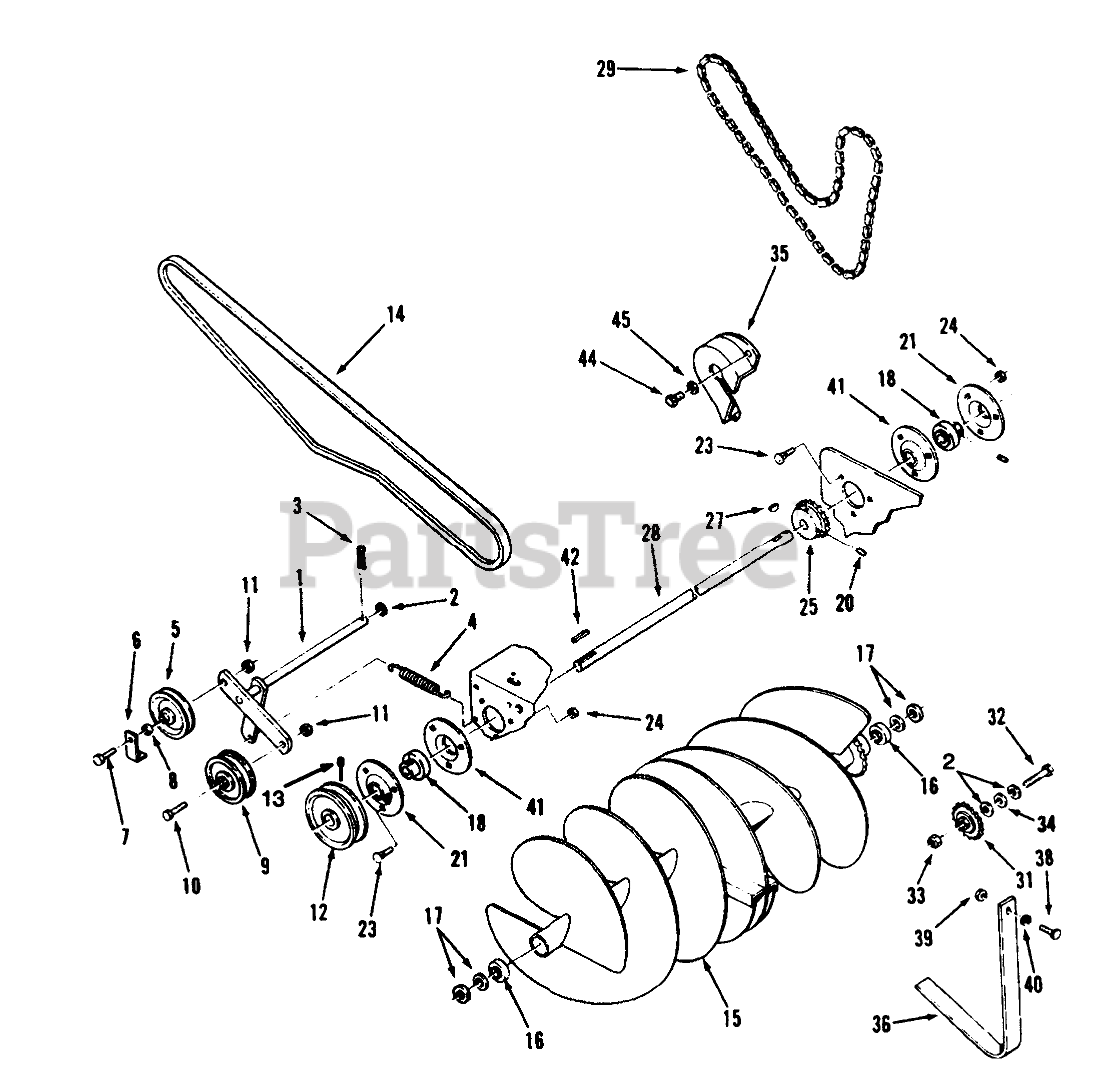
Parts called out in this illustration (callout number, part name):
1	Arm Idler
2	WASHER-FLAT
3	PIN-COTTER
4	SPRING-EXTENSION
5	PULLEY-IDLER
6	Spacer
7	SCREW-HH
8	SPACER
9	PULLEY-IDLER, FLAT
10	SCREW-HH
11	NUT-LOCK, NI
12	PULLEY
13	SCREW-SQH
14	V-BELT
15	Auger
16	BEARING-BALL
17	WASHER-FLAT
18	BEARING AND COLLAR
20	SCREW-SET, HSH
21	FLANGE-ZERK RELUBE
23	BOLT-CARR
24	NUT-LOCK, NI
25	SPROCKET-14T H.T.
27	KEY-WOODRUFF
28	Shaft
29	CHAIN
31	Idler Sprocket
32	SCREW-HH
33	NUT-LOCK, NI
34	SPACER
35	GUARD-CHAIN
36	Guard
38	SCREW-HH
39	NUT-KEPS
40	WASHER-FLAT
41	Flange
42	KEY-STRAIGHT
44	Bolt
45	WASHER-FLAT
